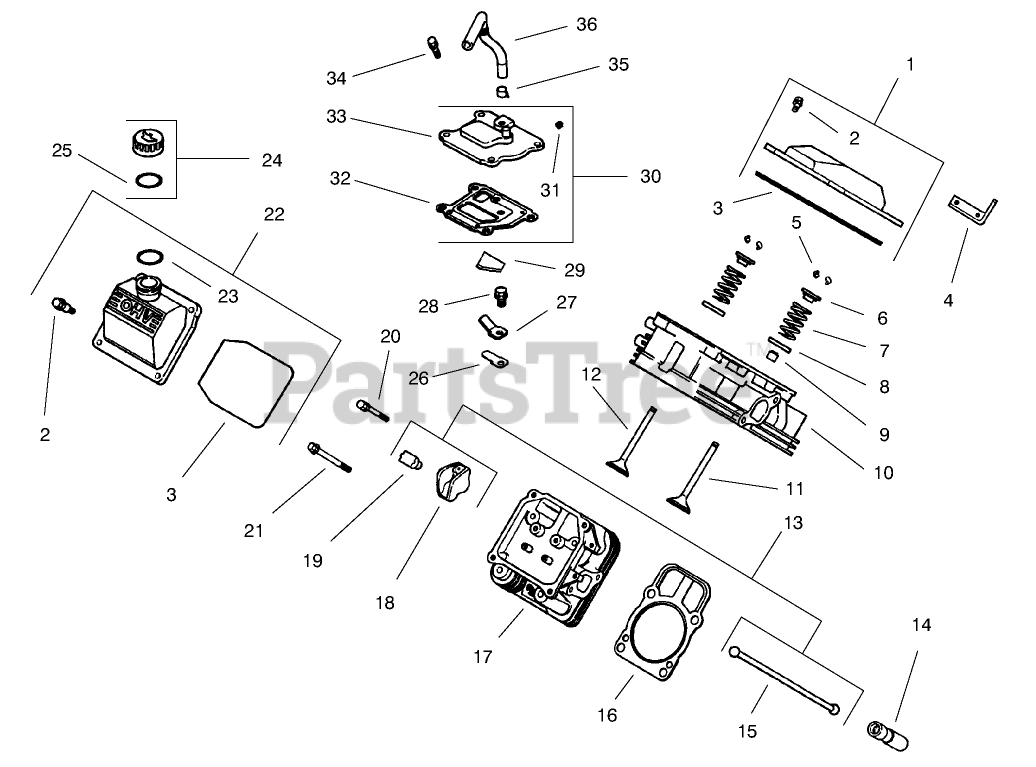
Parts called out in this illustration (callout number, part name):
1	Kit, valve cover-plain (Includes 2-3)
2	Screw
3	O-Ring
4	Strap-Lifting
5	Retainer Kit
6	Cap-Spring, Valve
7	Spring-Valve
8	Retainer-Spring
9	Seal-Stem, Valve
10	#1 Cylinder Head ASM
11	Valve-Intake
12	Valve-Exhaust
13	Kit, valve train (Includes 15, 18, 19)
14	Lifter-Valve
15	Rod-Push
16	Gasket, cylinder head
17	#2 Cylinder Head ASM
18	Arm-Rocker
19	Pivot-Arm, Rocker
20	Screw
21	Screw-HF
22	Kit, valve cover-oil fill (Includes 2, 3, 23)
23	O-Ring
24	Kit, oil fill cap (Includes 25)
25	"O"Ring
26	Reed
27	Retainer-Reed
28	Screw
29	Filter-Breather
30	Kit, breather (Includes 31-33)
31	Plug
32	Gasket-Breather
33	Cover-Breather
34	Screw
35	Clamp
36	Hose-Breather
